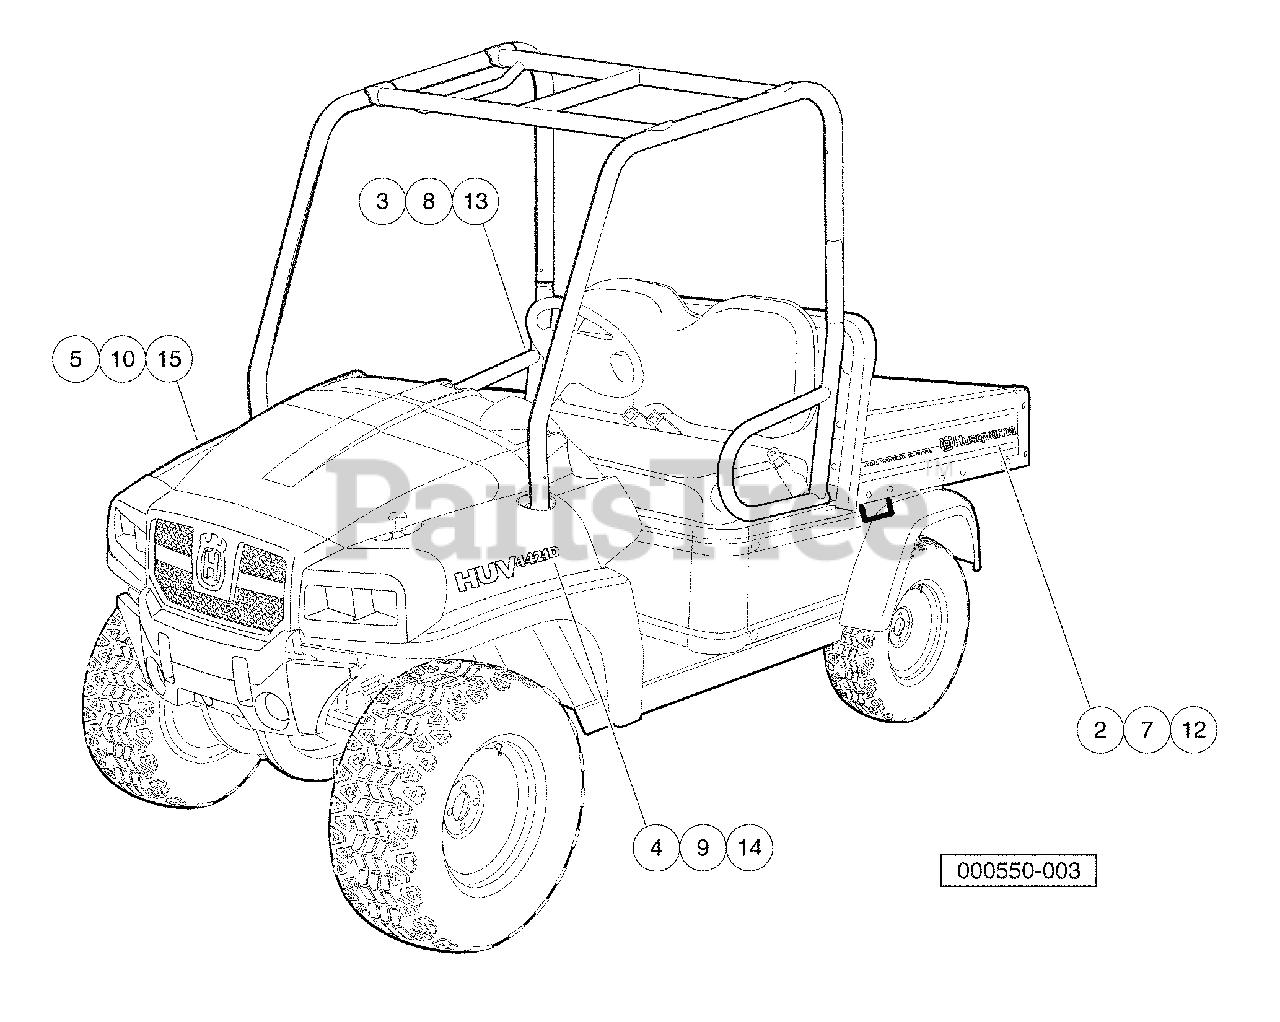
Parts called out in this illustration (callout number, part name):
1	Instl,decal,huv4421d, Moff
2	Decal, Bed, Huv, Moff, Ds
3	Decal, Bed, Huv, Moff, Ps
4	Decal, Huv 4421d, Moff, Ds
5	Decal, Huv 4421d, Moff, Ps
7	Decal, Bed, Huv, Orange, Ds
8	Decal, Bed, Huv, Orange, Ps
9	Decal, Huv 4421d, Orange, Ds
10	Decal, Huv 4421d, Orange, Ps
11	Instl,decal,huv4421d,olv Grn
12	Decal, Bed, Huv, Olv Grn, Ds
13	Decal, Bed, Huv, Olv Grn, Ps
14	Decal, Huv 4421d, Olv Grn, Ds
15	Decal, Huv 4421d, Olv Grn, Ps
